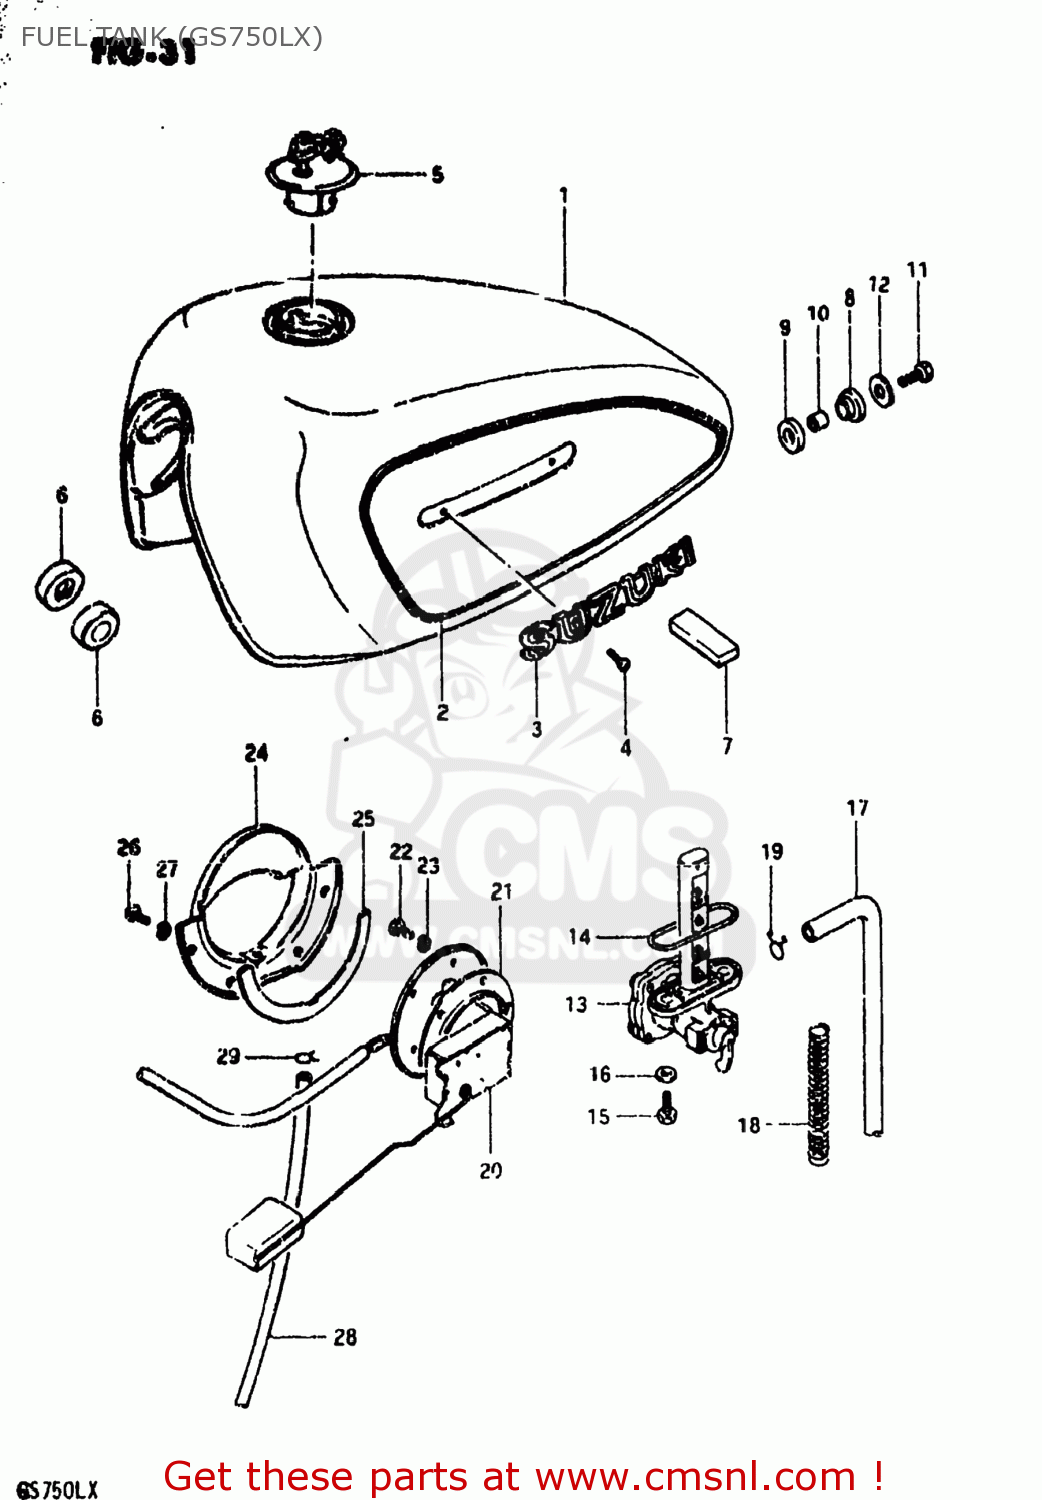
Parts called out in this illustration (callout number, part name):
1	TANK ASSEMBLY,FUEL
2	TAPE SET,FUEL TANK
3	EMBLEM
4	SCREW 3X6
5	CAP SET,FUEL TANK
6	CUSHION
7	CUSHION
8	CUSHION
9	CUSHION
10	SPACER(8.5X12X19)
11	BOLT (8X30)
12	WASHER (8.5X29X1.6)
13	COCK ASSEMBLY,FUEL
14	O RING
15	SCREW (6X25)
16	GASKET
17	HOSE
18	SPRING
19	CLIP
20	GAUGE ASSEMBLY,FUEL LEVEL
21	GASKET,FUEL LEVEL GAUGE (NAS)
22	BOLT
23	LOCK WASHER
24	PLATE,FUEL DRAIN
25	GASKET,FUEL DRAIN PLATE (NAS)
26	SCREW
27	LOCK WASHER
28	HOSE,FUEL
29	CLIP
